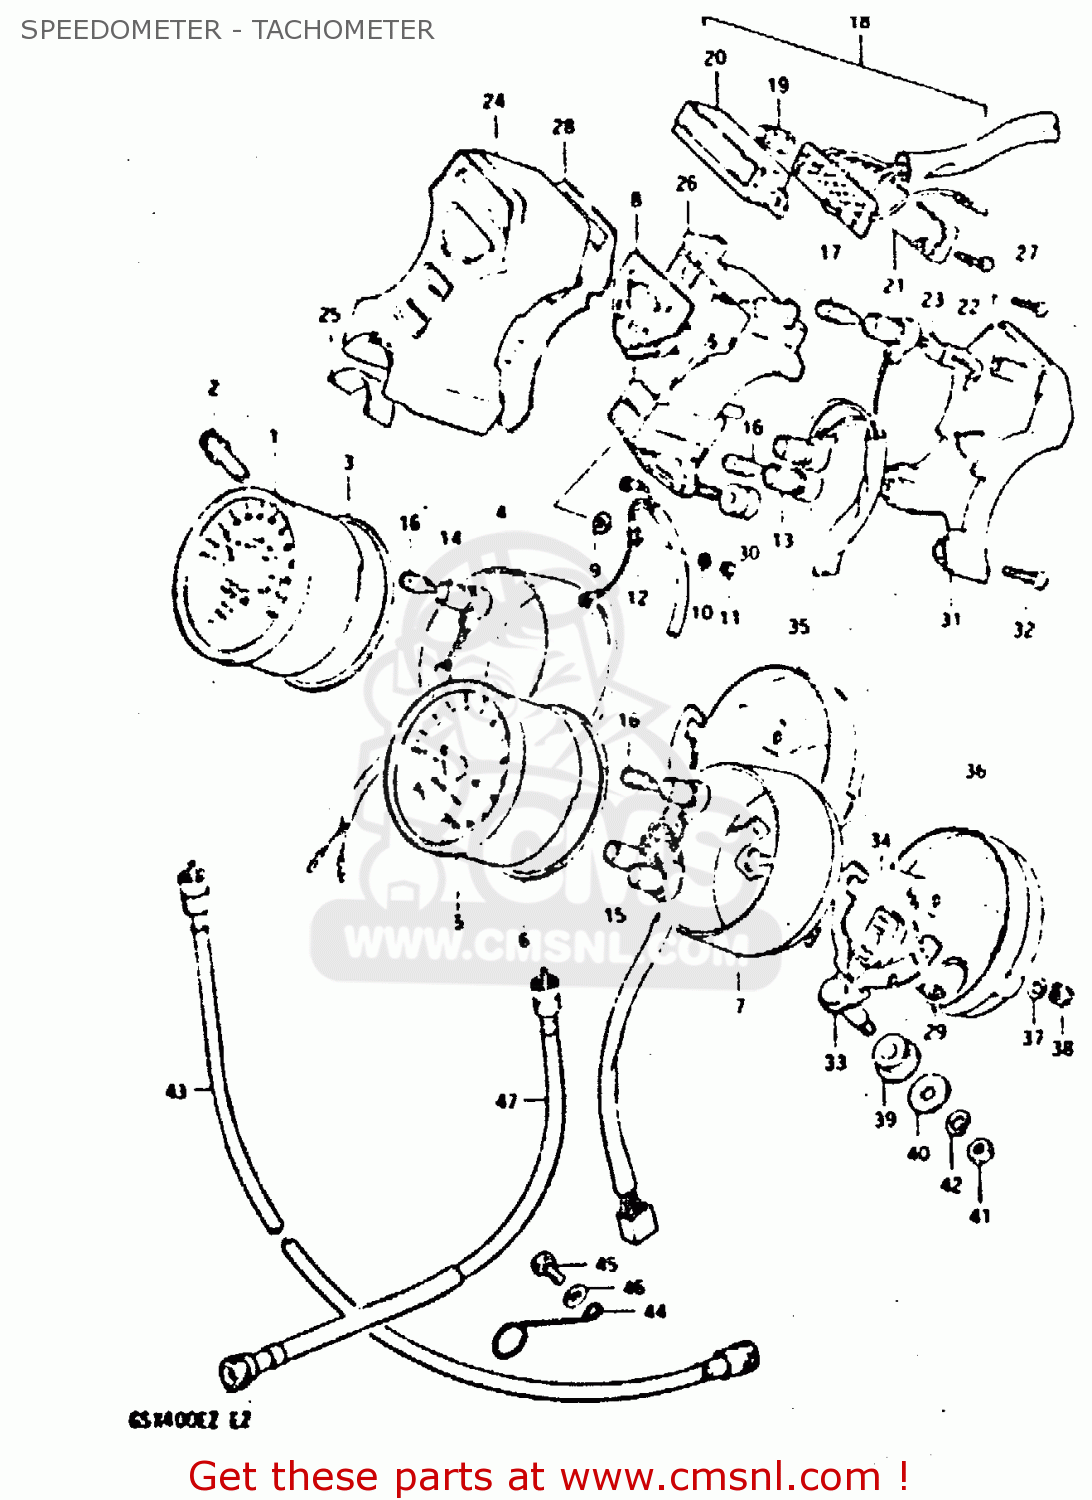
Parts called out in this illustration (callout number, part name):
1	SPEEDOMETER (MILE/KILO)
2	KNOB
3	CUSHION,SPEEDOMETER
4	COVER,SPEEDOMETER
5	TACHOMETER
6	CUSHION,SPEEDOMETER
7	COVER,TACHOMETER
8	METER,FUEL
9	WASHER,FUEL METER
10	LOCK WASHER
11	NUT 3MM
12	LEAD WIRE, FUELMETER
13	SOCKET,PILOT CASE
14	SOCKET,METER
15	SOCKET,TACHOMETER
16	BULB(12V3.4W,T10)
17	BULB(12V1.7W,T10,WB121)
18	INDICATOR ASSEMBLY,GEAR POSITION
19	BULB(14V1.12W)
20	CASE,GEAR INDICATOR
21	COVER,LWR
22	SCREW,GEAR INDICATOR
23	CLAMP,CORD
24	CASE,PILOT BOX
25	SEAL,IGNITION SWITCH
26	CASE,PILOT BOX,INNER
27	SCREW,INDICATOR
28	PLATE,PILOT BOX
29	CUSHION
30	CUSHION,PILOT BOX
31	COVER,PILOT BOX,UNDER
32	SCREW
33	BRACKET,COMBINATION METER
34	CUSHION,METER
35	COVER,METER,UNDER
36	PLATE,TACHOMETER UNDER
37	WASHER
38	NUT
39	CUSHION,METER BRACKET
40	WASHER (8.5X29X1.6)
41	NUT
42	LOCK WASHER
43	CABLE ASSY,SPEEDOMETER
44	CLAMP,SPEEDOMETER CABLE
45	BOLT, UPPER
46	WASHER
47	CABLE ASSEMBLY,TACHOMETER
